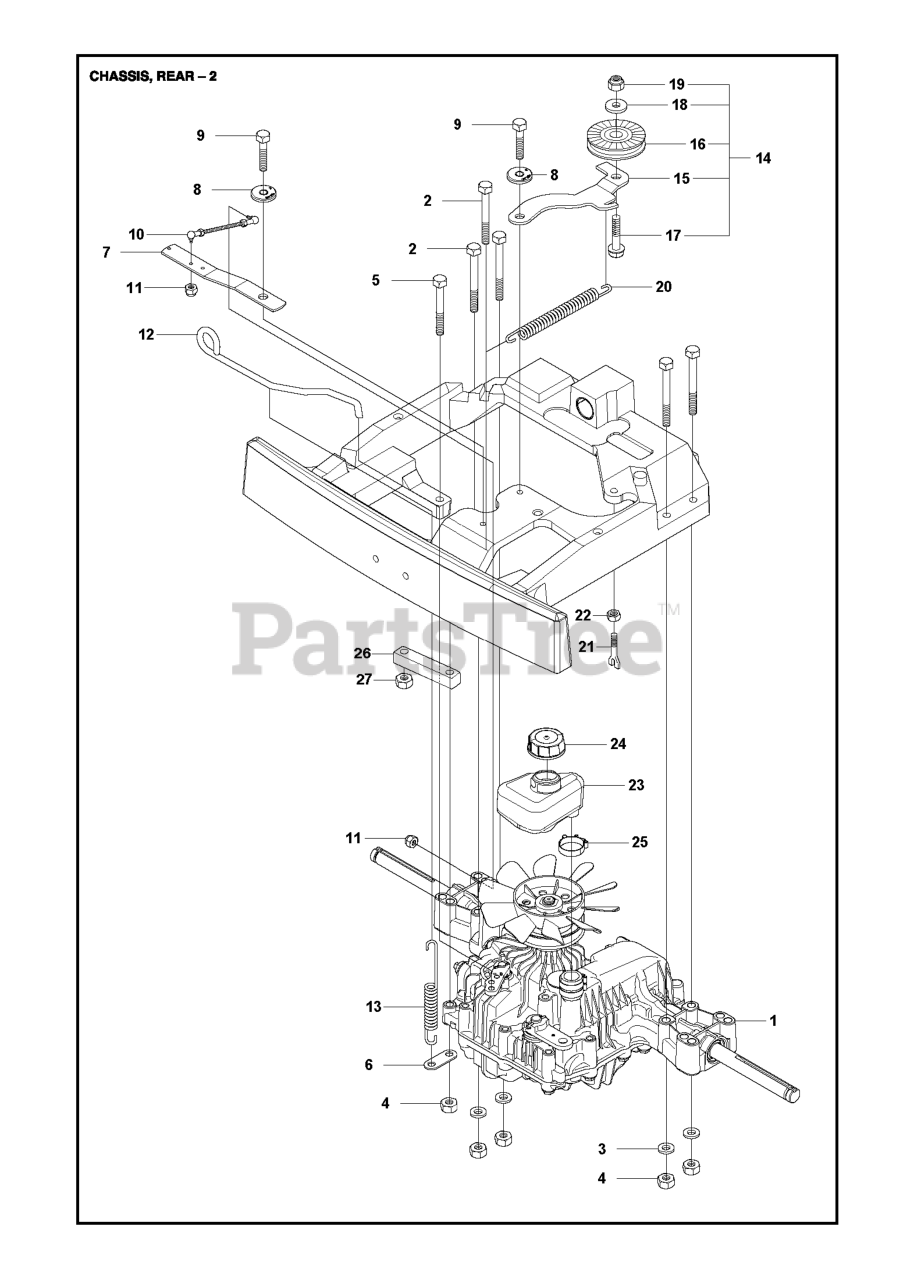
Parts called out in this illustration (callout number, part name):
1	HYDROSTAT 7A646024070
3	WASHER BRB 8.4X17
4	NUT
5	SCREW
8	WASHER
8	Washers
9	SCREW
11	LOCKNUT M5
15	TENSIONER
15	BELT TENSIONER ARM
17	SCREW
19	LOCKNUT M8
24	TANK CAP
24	TANK CAP ASSY
25	HOSE CLAMP 20-32
26	BRACKET
27	NUT
